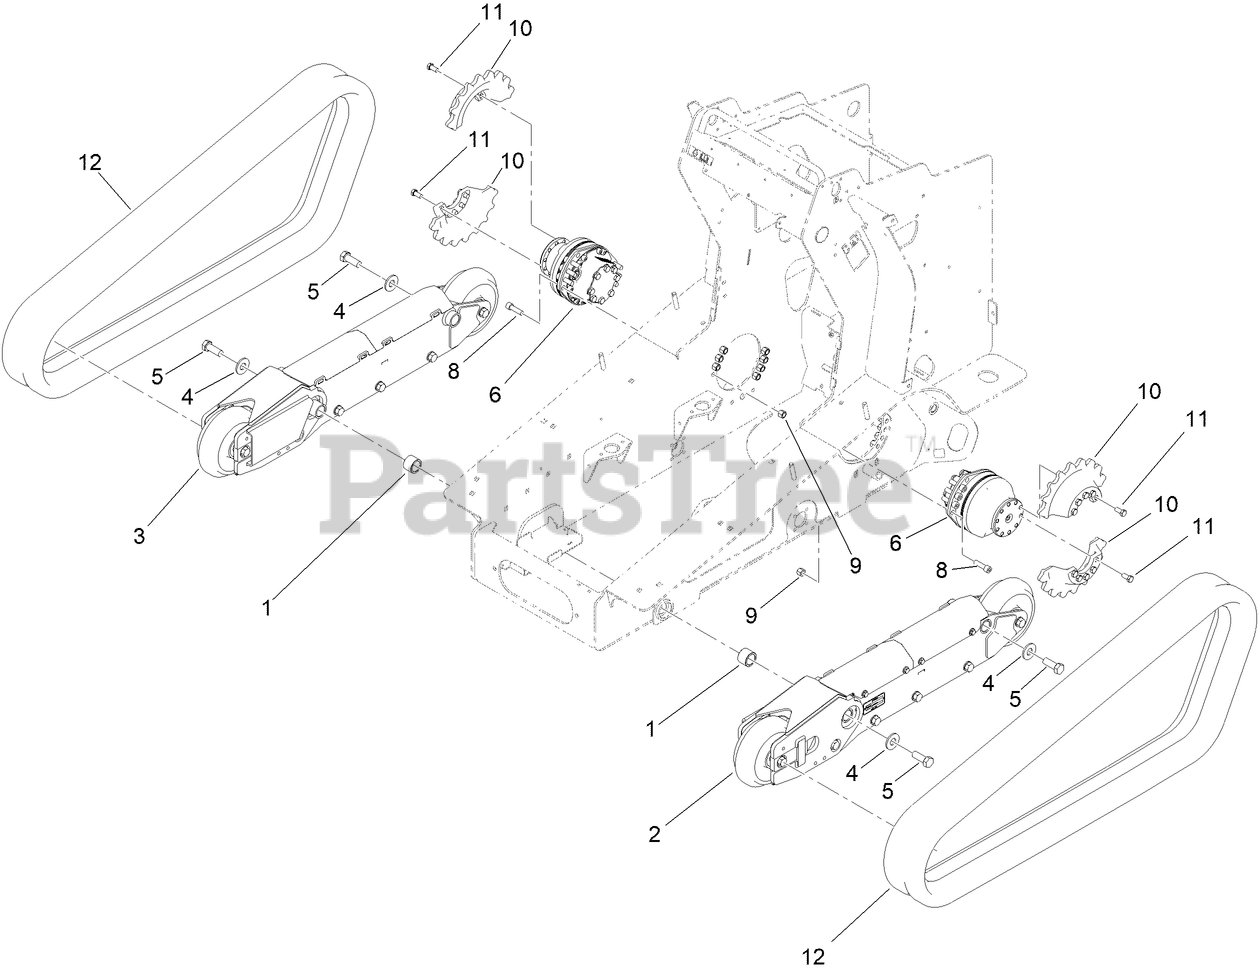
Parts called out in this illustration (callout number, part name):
1	SPACER-TRACK
2	TRACK ASM-LH
3	TRACK ASM-RH
4	WASHER
5	SCREW-HH
6	WHEELMOTOR ASM
8	SCREW-HSH
9	NUT-LOCK, NI
10	SPROCKET-DRIVE
11	SCREW-HH
12	TRACK-WIDE,
